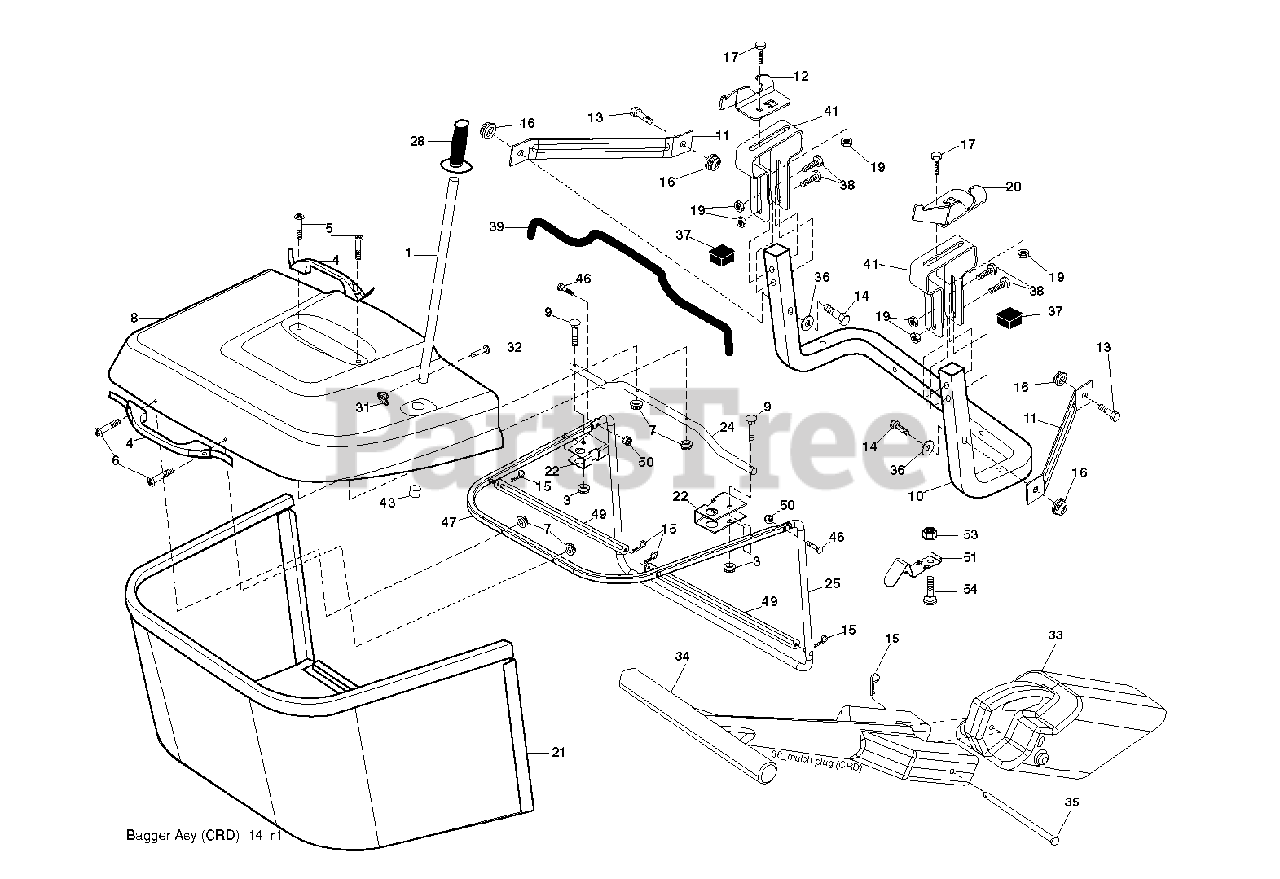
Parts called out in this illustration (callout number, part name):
1	TUBE HANDLE
3	NUT T
5	SCREW.PAN.HEAD
11	BRACKET
14	BOLT-HEX EAK
15	RETAINER-SPRNG RB
16	NUT LOCK FLG 3/8-16 UNC
17	BOLT
19	NUT LOCK HEX FLANGE 5/16-18
20	BRKT.PIVOT.RH.CRD
21	BAGGER.ASM.CRD.2007
22	BRACKET
24	TUBE
28	GRIP.HANDLE.BLACK
31	RETAINER CLIP
32	RIVET,DRILLED
33	PLUG
35	PIN
38	BOLT.5/16-18X2.5
39	SEAL.BAGGER.CRD
41	BRKT, BAGGER
43	PLUG, TUBING END
46	BOLT.CARRIAGE.5/16-18
50	NUT.71038.31-18.HEX.NYLOCK
53	NUT
54	BOLT
